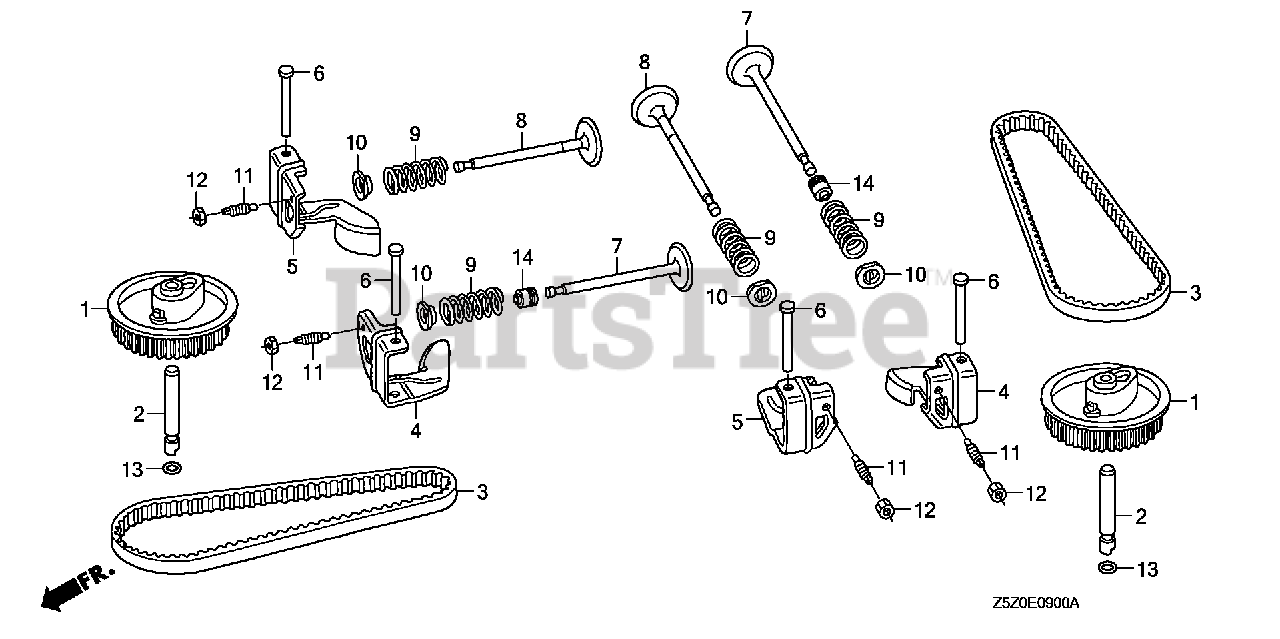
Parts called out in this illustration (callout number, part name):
1	PULLEY, CAMSHAFT
2	SHAFT, CAM PULLEY
3	BELT, TIMING (97HU8 G-200)
4	ARM, IN. VALVE ROCKER
5	ARM, EX. VALVE ROCKER
6	SHAFT, ROCKER ARM
7	VALVE, IN.
8	VALVE, EX.
9	SPRING, VALVE
10	RETAINER, IN. VALVE SPRING
10	RETAINER, VALVE SPRING
11	SCREW, TAPPET ADJUSTING
12	NUT, TAPPET ADJUSTING
13	O-RING (6.8X1.9) (ARAI)
14	SEAL, VALVE STEM
